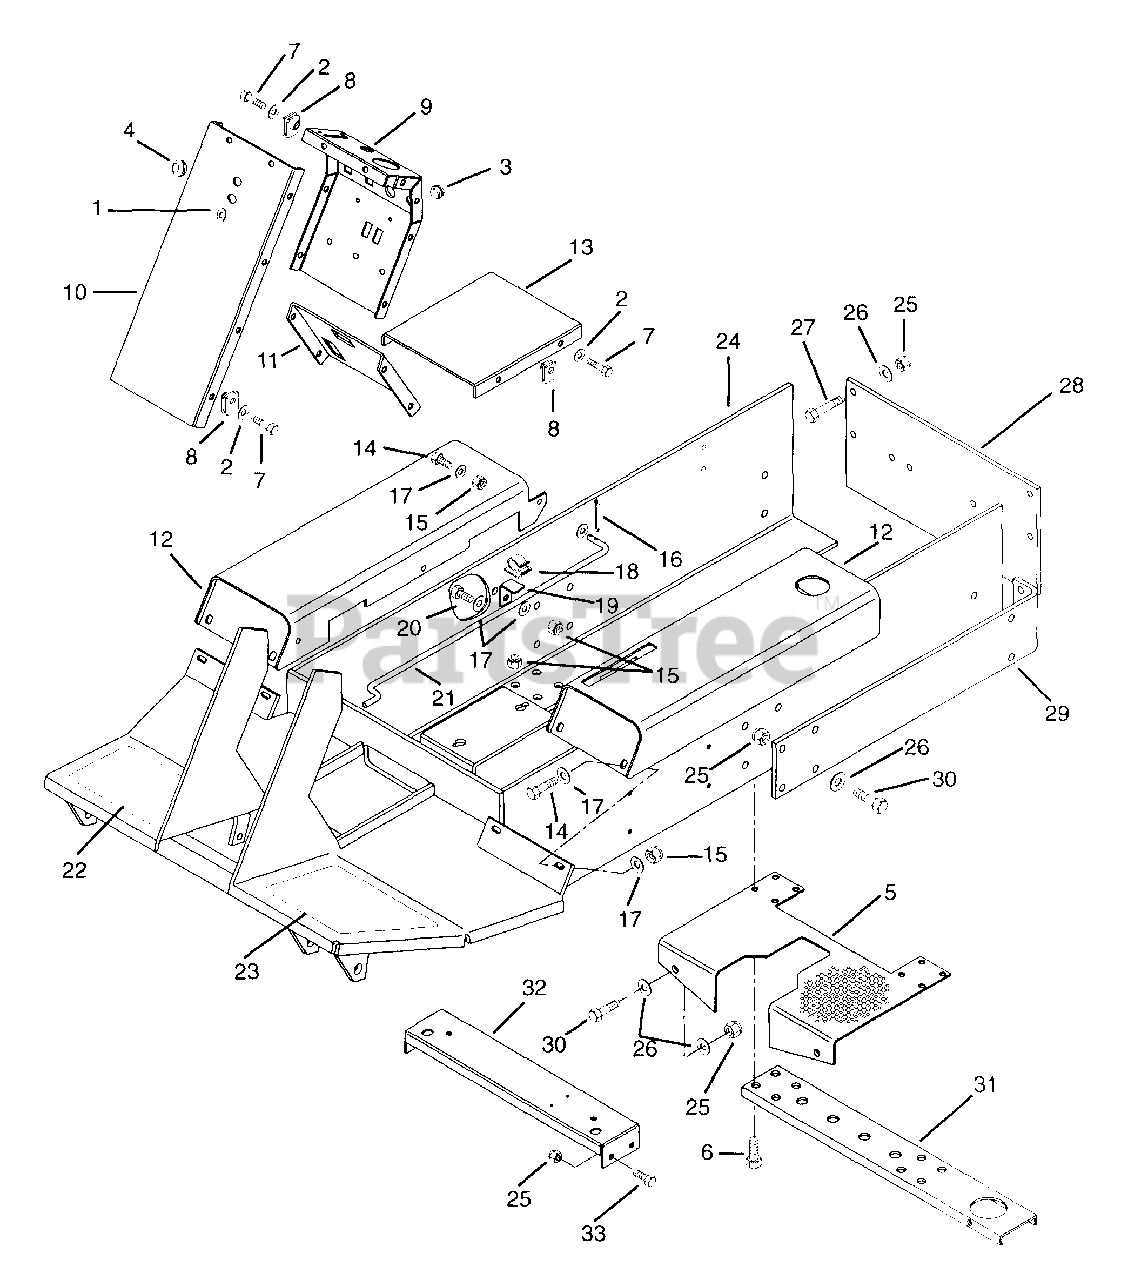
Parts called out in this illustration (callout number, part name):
1	Washer-Flat-Steel .328 x 1.0 x .094
2	Washer-Flat-Steel .281 x .625 x .065
3	Grommet .062 x .312
4	Weldment, Rollover Bar
6	Bolt-Hex .38-16 x 1.25 Grade 5
7	Screw-Machine .25-20
8	Nut-Retainer .25-20 x .56
9	Panel, Instrument
10	Panel, Front
11	Panel, Brake Lock
12	Weldment, Fender Right Hand
12	Weldment, Fender Left Hand
13	Panel, Access
14	Bolt-Hex .380-16 x .875
15	Nut-Locking-Nylon .375-16 Grade 2
16	Pin-Cotter .09 x .75
17	Washer-Flat-Steel .406 x .812 x .065
18	Clip, Wire
19	Bracket, Stay Rod
20	Bolt-Hex .38-16 x 1.00 Grade 5
21	Rod, Stay
22	Cover, Right Hand Foot
23	Cover, Left Hand Foot
24	Weldment, Frame
25	Nut-Locking-Nylon .50-13 Grade 5
26	Washer-Flat-Steel .531 x 1.062 x .095
27	Bolt-Hex .50-13 x 1.50 Grade 5
28	Plate, Bumper - 22 lbs
28	Plate, Bumper - 37 lbs
29	Bumper, Kubota Frame
30	Bolt-Hex .50-13 x 1.25 Grade 5 (989051,300)
30	Bolt-Hex .50-13 x 1.75 Grade 8 (989052,301)
31	Bracket, Frame
32	Bracket, Deck Plate
33	Bolt-Hex .50-13 x 1 Grade 5
